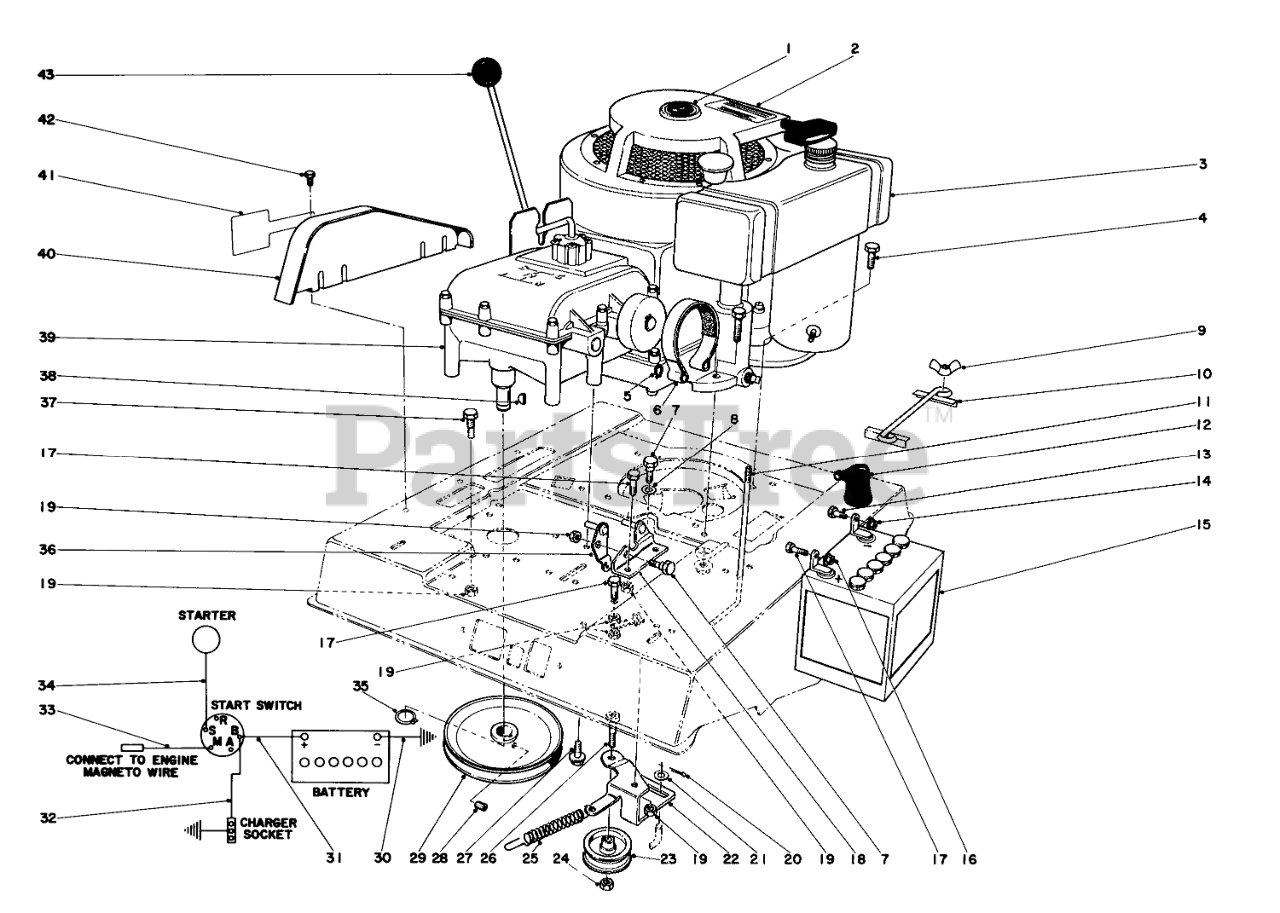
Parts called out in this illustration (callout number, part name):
1	Decal
2	Caution Decal
3	Engine (Model 56100)
4	SCREW-HH
5	RING-GRIP
6	Brake Band
7	Screw
8	Washer
9	Wing Nut
10	Clamp
11	Battery Bolt
12	BATTERY BOOT
13	SCREW-HH
14	NUT-HF
15	Battery
16	NUT-HF
17	SCREW-HH
18	Bracket
19	Nut
20	PIN-COTTER
21	WASHER-PLAIN
22	Idler Lever
23	Idler Pulley
24	NUT-LOCK, SIDE
25	Clutch Spring
26	Capscrew
27	SCREW-HHF
28	SCREW-SET, HSH
29	Pulley
30	Ground Wire (56150)
31	Wire (Model 56150)
32	Wire (Model 56150)
33	Wire (Model 56150)
34	Wire (Model 56150)
35	RING-SNAP, EXTERNAL
36	Pivot
37	Screw
38	KEY-WOODRUFF
39	Transmission
40	Chain Guard
41	Decal Shift Pattern
42	SCREW-HWH
